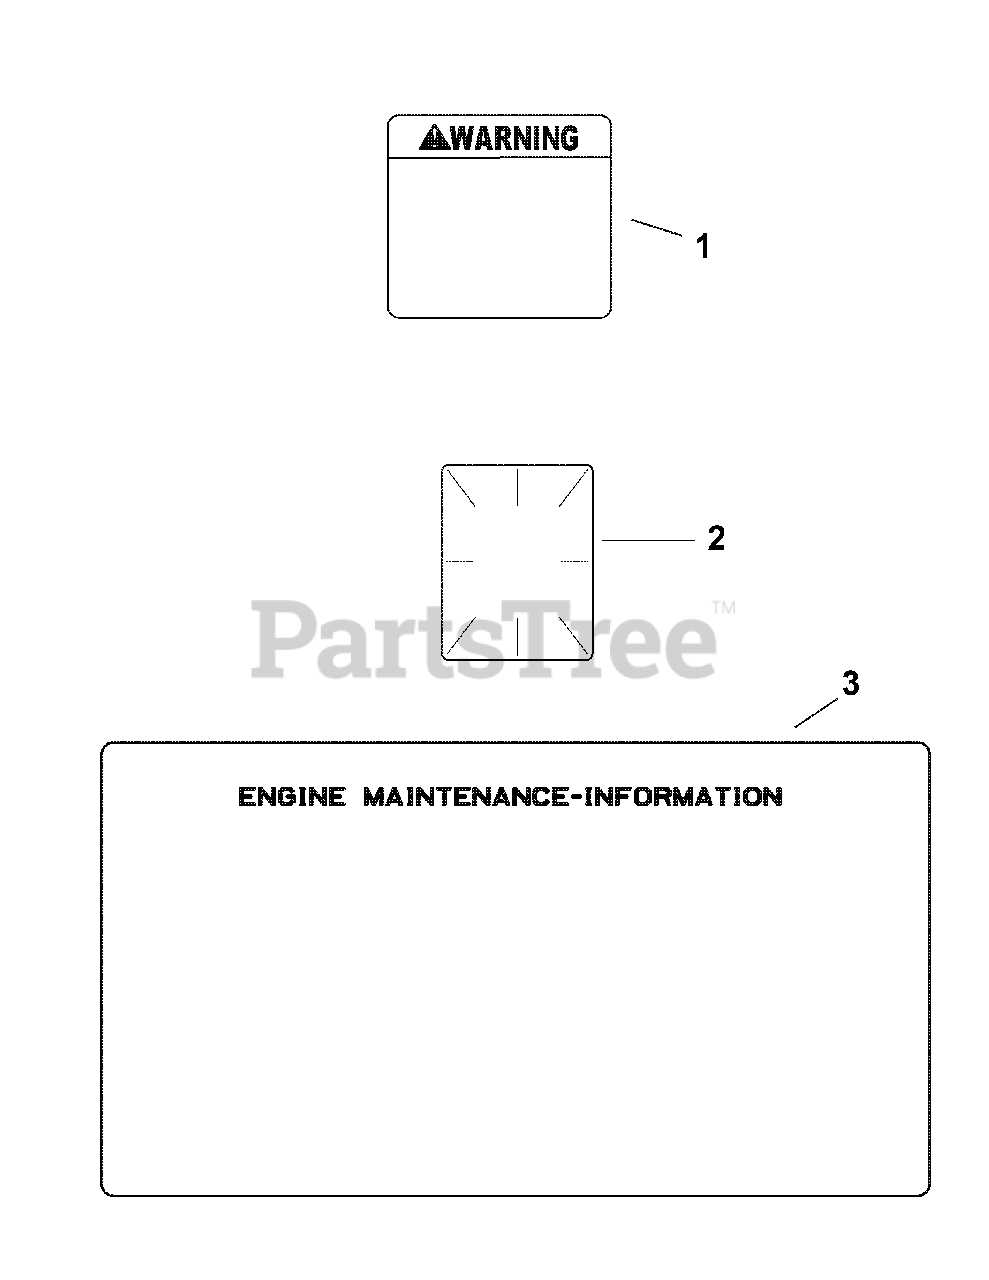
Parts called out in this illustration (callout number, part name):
1	Decal, Warning
2	Decal, Clear Laminate
3	Decal, Engine Maint.
